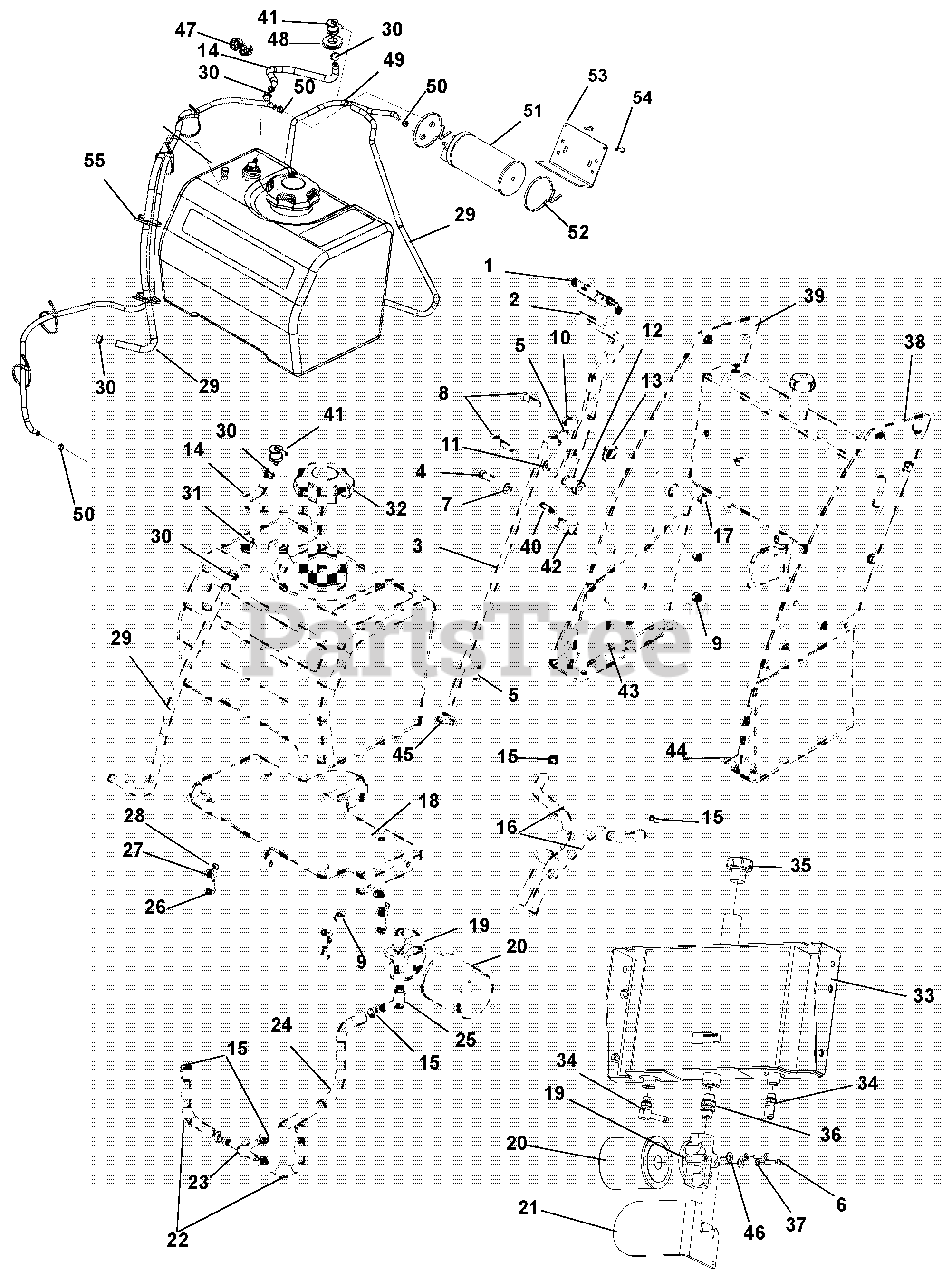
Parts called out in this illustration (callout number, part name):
1	GRIP, PVC .250 X 1.00 X 3.63
2	LEVER, HAND BRAKE FLOAT WALK
3	ROD, DRIVE CONTROL FW
4	BOLT, HEX .38-16 X 1.00
5	RING, RUE .375 X .054 X 1.254
6	BOLT, HEX .25-20 X 1.00 GR5 Y
7	WASHER, FL-STL .406 X .812 X .065
8	BOLT, HEX .38-16X1.50 GR5 Y
9	NUT-LOCKING-NYLON .38-16
10	NUT-SPNLK-FLG .375-16
11	WASHER-FL-STL .38 X .875 X .083
12	BUSHING, BRAKE LEVER STAND OFF
13	GROMMET: RUB:.88ID X 1.38OD X .14GR
14	HOSE, FUEL HYDRO TANK - ROV
15	CLAMP, HOSE - 1/2" PINCH
16	HOSE, HYD .375 X 10
17	NUT, LK-CTR .38-16
18	BRACKET, FUEL TANK RMHF
19	HEAD, OIL FILTER
20	FILTER, OIL
21	GUARD, HYDRO FILTER FLWLK
22	HOSE, HYD 3/8 X 6.00
23	FTG, TUN 3/8 HOSE
24	HOSE, HYD. .375 X 12
25	FTG, 90 BRB-OR 4601-06-08
26	BOLT, HEX .38-16 X .75 GR5 Y
27	WASHER, LK .38 X .094 REG
28	WASHER, FL-STL .406 X .812 X .065
29	HOSE, FUEL 1/4 X 15.00
30	CLAMP, FUEL LINE
31	TANK, FUEL
32	CAP, FUEL NONVENT, AUTOLOCK
33	WLDT, TANK
34	FTG, 90 9/16 MOR X 3/8 HOSE
35	CAP, OIL FILL BREATHER
36	STRAIGHT UNION SAE 8
37	WASHER, LK .25 X .062 REG
38	WLDT, LH UPRIGHT TOWER 36
39	WLDT, RH UPRIGHT TOWER 36
40	SCREW, 10-24 X .75 HWH
41	VALVE, REMOTE ROLL OVER
42	SWITCH- DOUBLE POLE N.O./N.O.
43	PLATE, DOUBLE RH UPRIGHT BI
44	PLATE, DOUBLE LH UPRIGHT BI
44	PLATE, LH DOUBLER 36" GRAVELY
45	SWIVEL, 3/8-24
46	WASHER-FLAT-STL .312 X .734 X .065
47	BUSH, PANEL SNAP .687X.875X.56
48	GROMMET, REMOTE ROV
49	CLAMP, DBL PINCH 5/16" - 7/16"
50	CLAMP - HOSE, SPRING .188
51	400 CC CARBON CANISTER 3/16 PT
52	CABLE TIE, .19 X 14.4
53	BRKT, CARB CANISTER MTG
54	SCR-MCH 10-24X.75 HWH YWZC
55	CABLE TIE, .15 X 8.50
